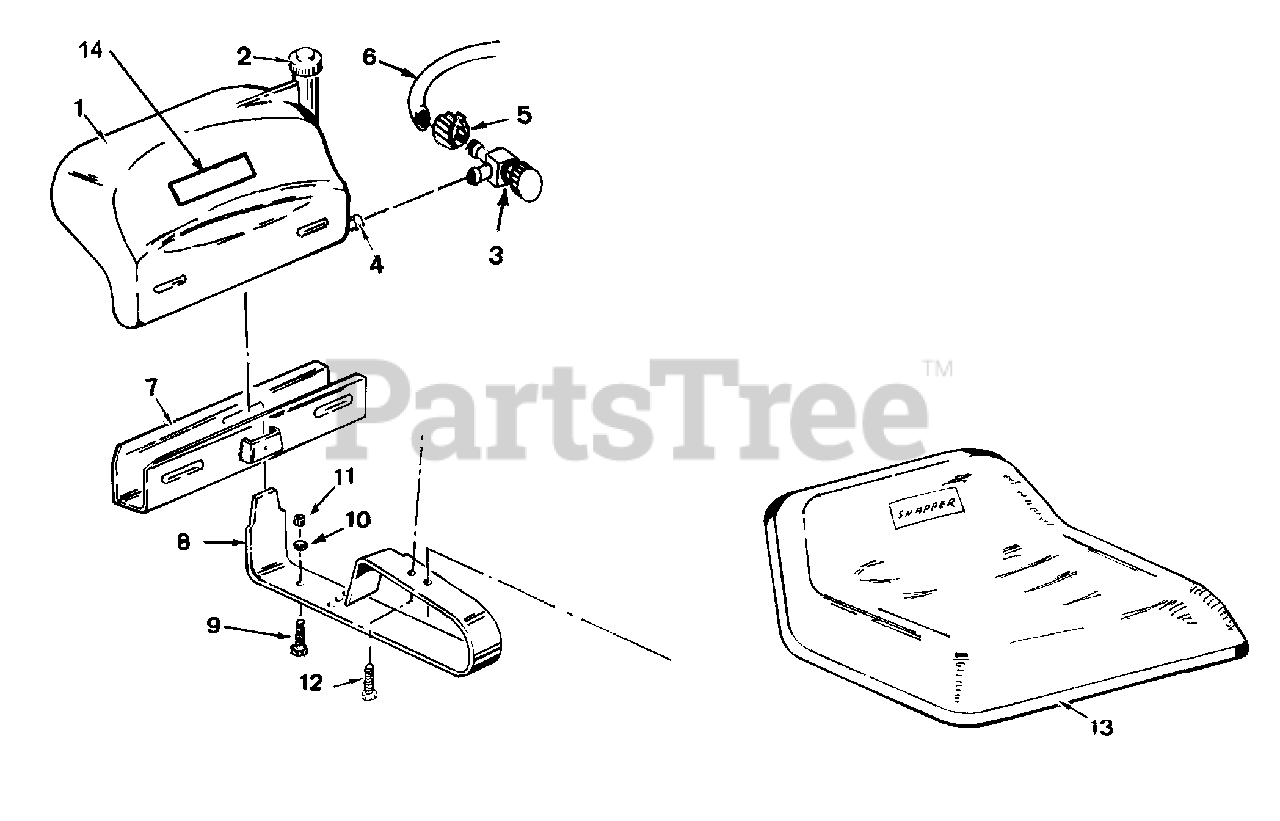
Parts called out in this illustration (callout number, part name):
1	TANK, Fuel
2	CAP, Gas Filler
3	VALVE, Fuel Shut-Off
4	GROMMET, Fuel Valve
5	CLAMP, Fuel Line
6	HOSE, Fuel
7	BRACKET, Tank
8	SPRING, Seat
9	CAPSCREW, 3/8-16 x 1
10	LOCKWASHER, 3/8 Int. Tooth
11	NUT, 3/8-16 Hex
12	CAPSCREW, 1/2-13 x 7/8 Special Grade 5
13	SEAT, Operator's
14	DECAL, Fuel Tank
